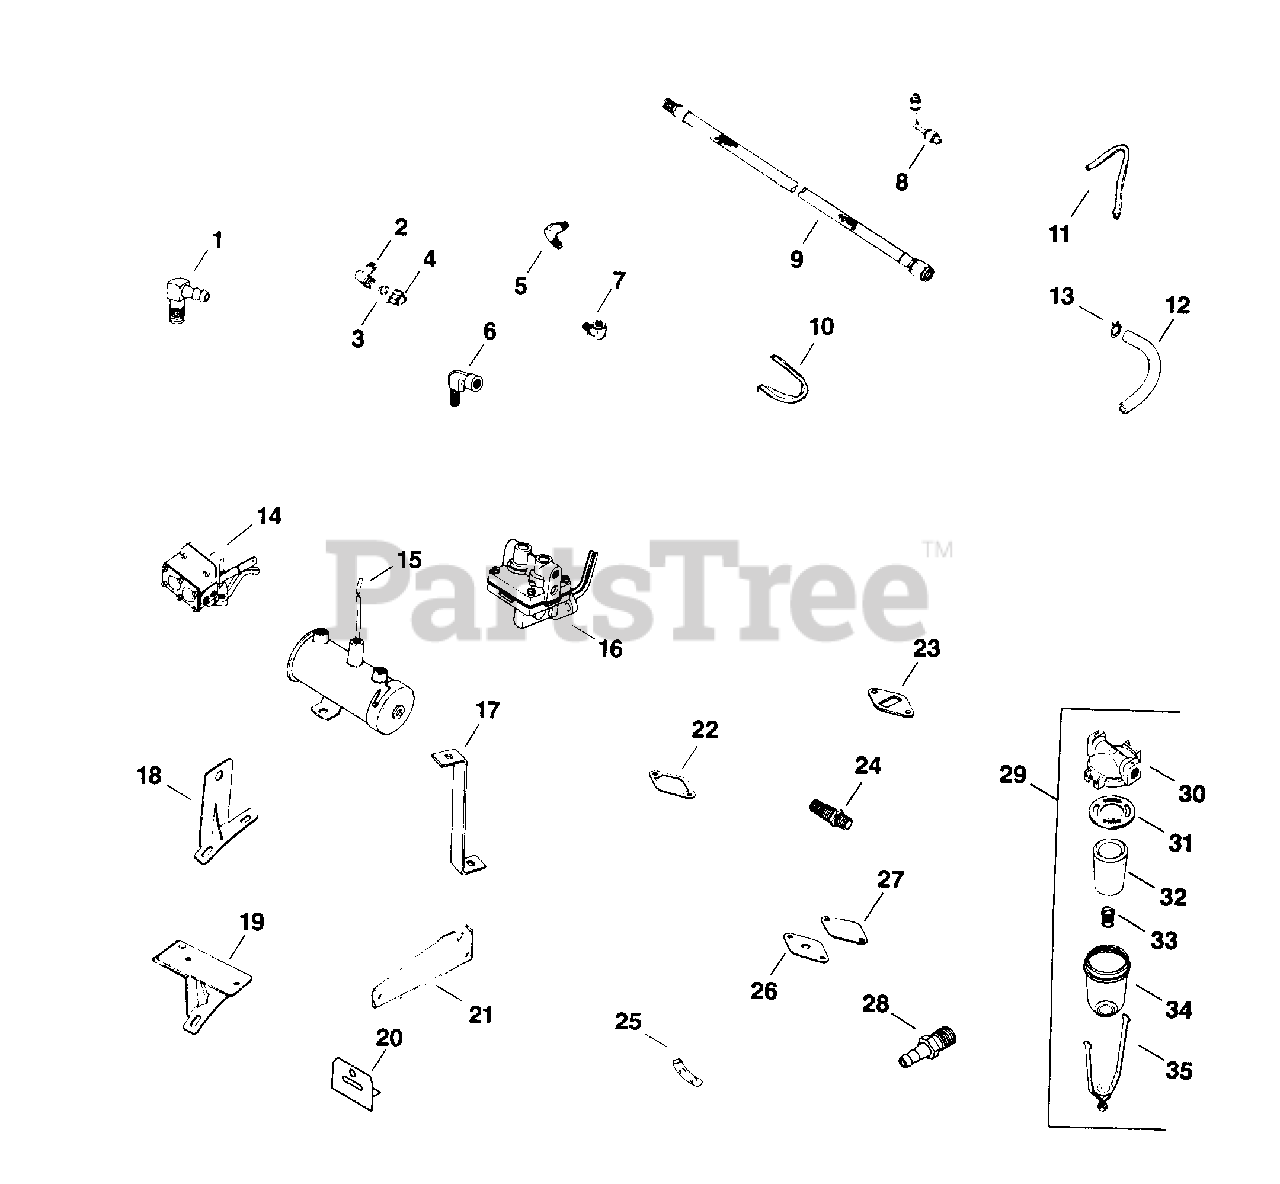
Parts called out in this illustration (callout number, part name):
1	CONNECTOR, 90 DEG. HOSE
2	ELBOW - (#DSC)
4	NUT - (#DSC)
11	LINE - DISCONTINUED
12	LINE
13	CLAMP, HOSE 1/2" USE 25 237 14-S
22	GASKET - USE 25 041 05
24	NIPPLE - DISCONTINUED
29	FILTER - (#DSC)
31	GASKET - DISCONTINUED
32	ELEMENT - DISCONTINUED
33	SPRING - DISCONTINUED
35	RETAINER - DISCONTINUED
271736-S	KIT, DIAPHRAGM - DISCONTINUED
